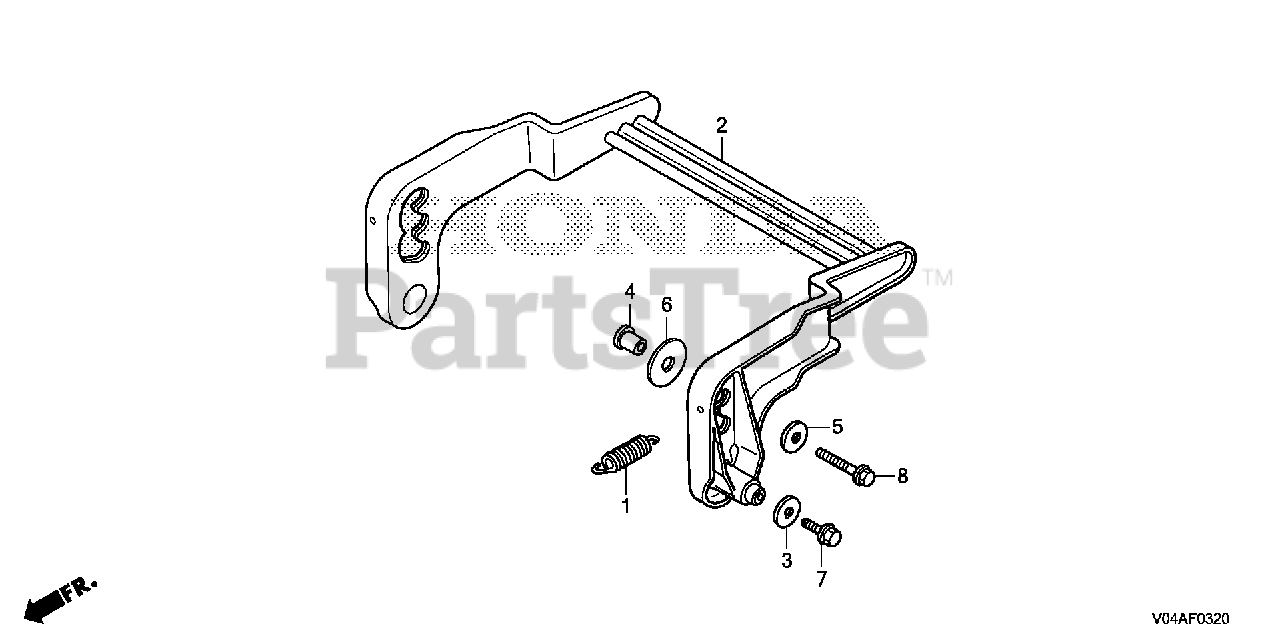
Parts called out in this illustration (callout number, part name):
1	SPRING, HEIGHT ADJUSTING
2	PLATE, HEIGHT ADJUSTING
3	WASHER, PLAIN (8X23X3.2)
4	COLLAR, HEIGHT ADJUSTING
5	WASHER, PLAIN (8MM)
6	WASHER, PLAIN (12MM)
7	BOLT, FLANGE (8X14)
8	BOLT, FLANGE (8X30)
